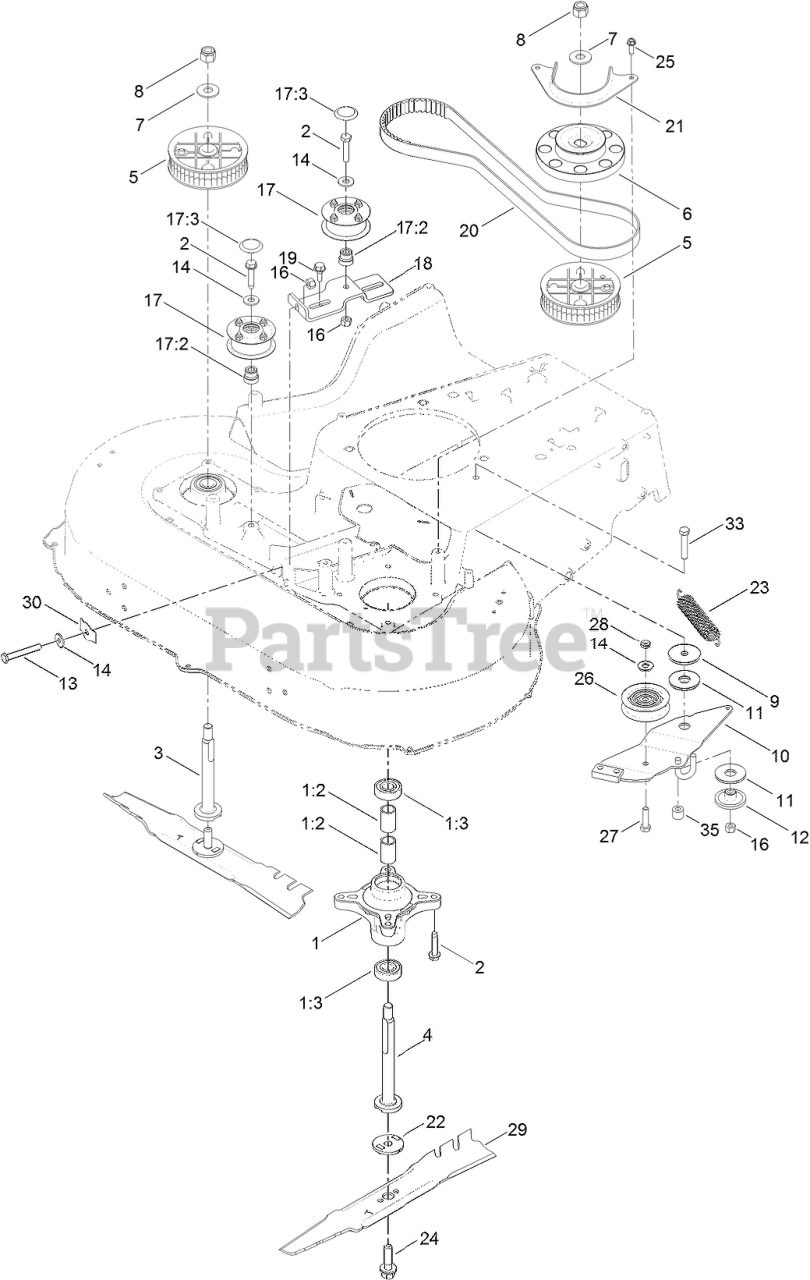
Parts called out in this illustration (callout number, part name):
1	SPINDLE ASM
1:2	SPACER
1:3	BEARING-BALL
3	SHAFT-SPINDLE
4	SHAFT-SPINDLE
5	SPROCKET
6	PULLEY-BRAKE, SPINDLE
7	WASHER-SPRING
8	NUT-HEX
9	WASHER-REBOUND
10	BRAKE ARM ASM
11	WASHER-FRICTION, COMPOSITE
12	SPACER
13	BOLT-TAP, HH
14	WASHER-FLAT
16	NUT-LOCK, NI
17	PULLEY KIT
17:2	ADAPTER-BORE
17:3	PLUG-CAP
18	BRACKET-IDLER
19	SCREW-SHOULDER, HHF
20	BELT-SYNCHRONOUS
21	GUIDE-BELT, SPINDLE
22	ADAPTER-BLADE
23	SPRING-EXTENSION, BRAKE
24	BOLT-BLADE
25	SCREW-HWHTF
26	PULLEY-IDLER
27	SCREW-HH
28	NUT-LOCK, NI
29	BLADE-ROTARY
30	SPRING-FLAT
33	SCREW-HH
35	HOSE-COOLANT
